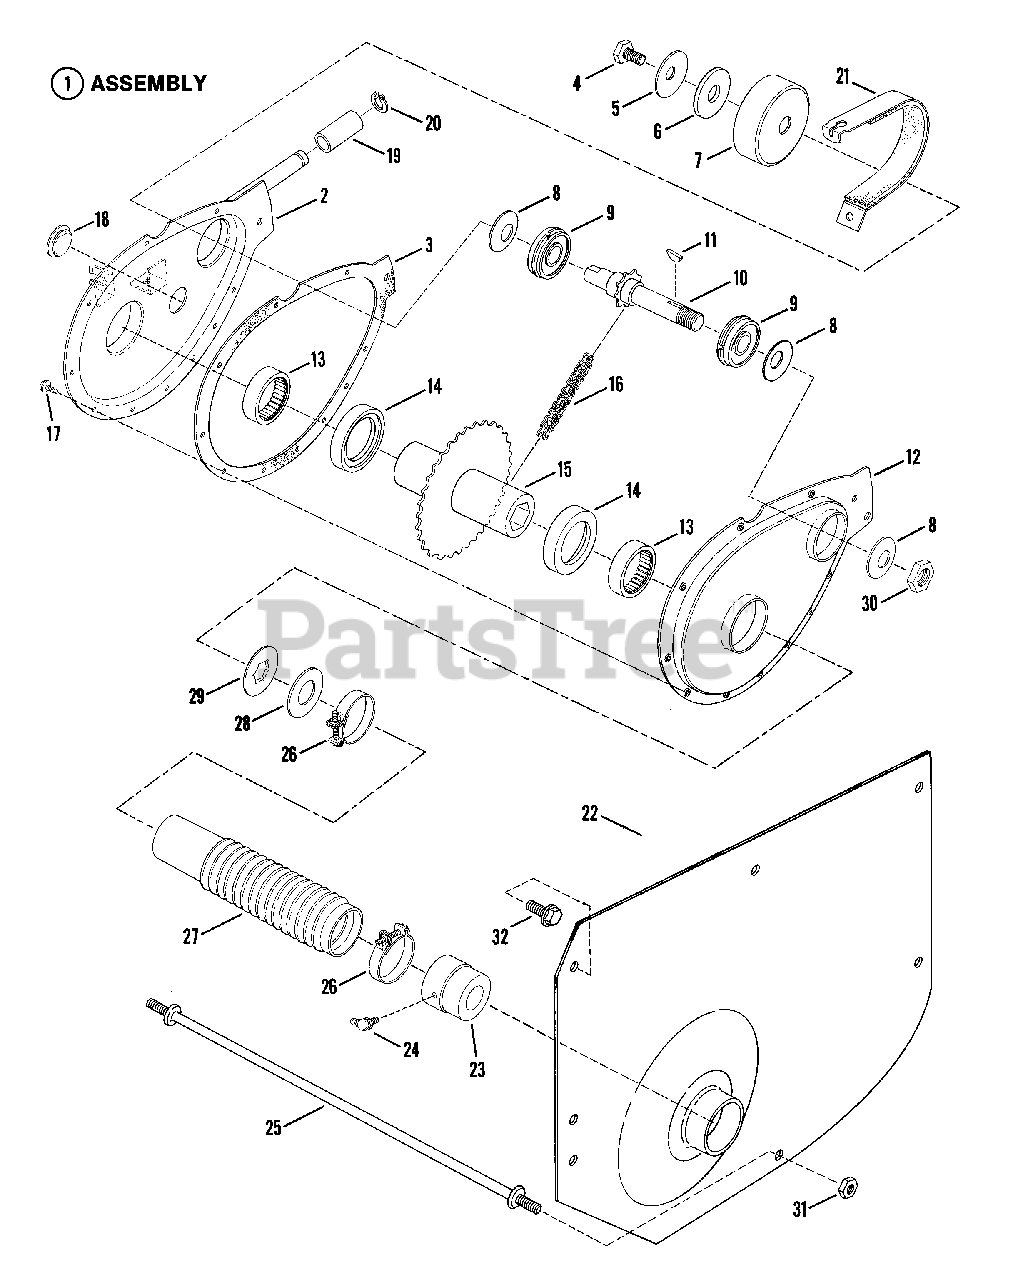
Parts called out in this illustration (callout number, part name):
1	ASSEMBLY, Chain Case
2	CASE, Sprocket
3	GASKET, Case Cover
4	SCREW, 3/8-24 x 1/2" Hex Head Cap
5	WASHER
6	WASHER, Brake Drum
7	DRUM, Auxiliary Brake
8	WASHER, Belleville
9	BEARING, Ball
10	SPROCKET & SHAFT
11	KEY, 1/8 x 5/8" Woodruff
12	COVER, Chain Case
13	BEARING, Needle
14	WASHER, Nylon Thrust
15	HUB & SPROCKET
16	CHAIN
17	SCREW, #10-24 x 1/2" Hex Washer Self-Tap (Torx)
18	PLUG, Oil Fill & Check
19	ROLLER
20	RING, Retaining
21	BAND, Auxiliary Brake
22	FENDER, Left Hand
23	BEARING, Fender
24	FITTING, Lube
25	ROD, Cross Tie
26	CLAMP, Boot
27	BOOT, Oil Seal
28	WASHER, Thrust (Nylon)
29	WASHER, Thrust
30	NUT, 5/8-18 Hex Center Lock
31	NUT, 5/16-24 Hex
32	SCREW, 5/16-18 x 5/8" Hex Washer Self-Tapping
